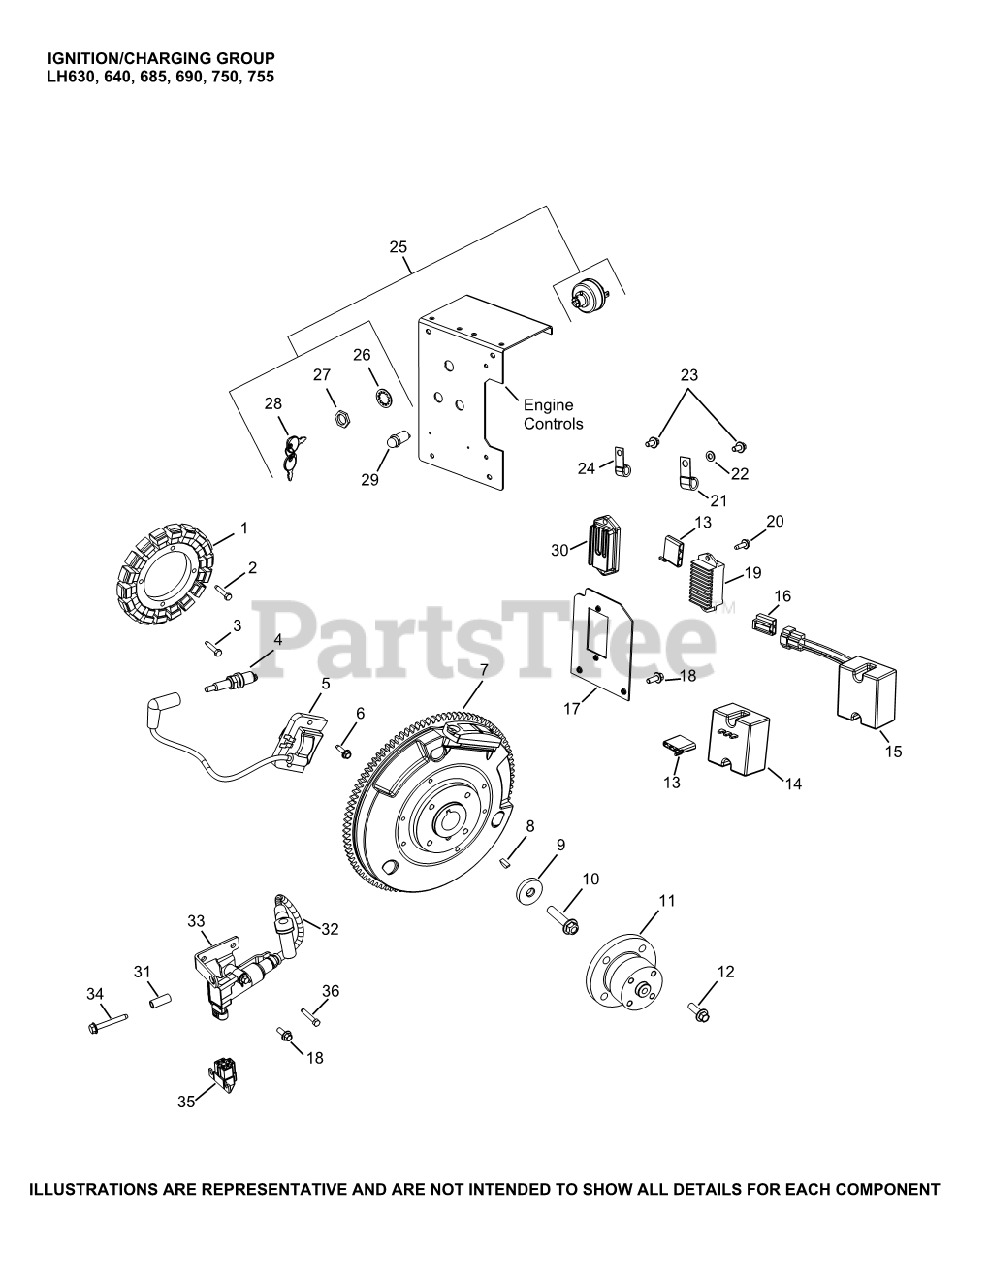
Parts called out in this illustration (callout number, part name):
2	SCREW, THREAD FORMING
4	SPARK PLUG
5	MODULE, IGNITION
7	FLYWHEEL (PAINTED)-USE 24 025 20-S
8	KEY, 3/16" X 5/8"
9	WASHER, FLAT 13/32"
10	SCREW, FLG M10X1.5X45 - (#25086361S)
13	CONNECTOR
20	SCREW, THREAD FORMING
21	CLIP, CABLE
22	WASHER, FLAT 1/4" (O.D. 1/2")
24	CLIP, CABLE
5217618-S	HARNESS, WIRING
